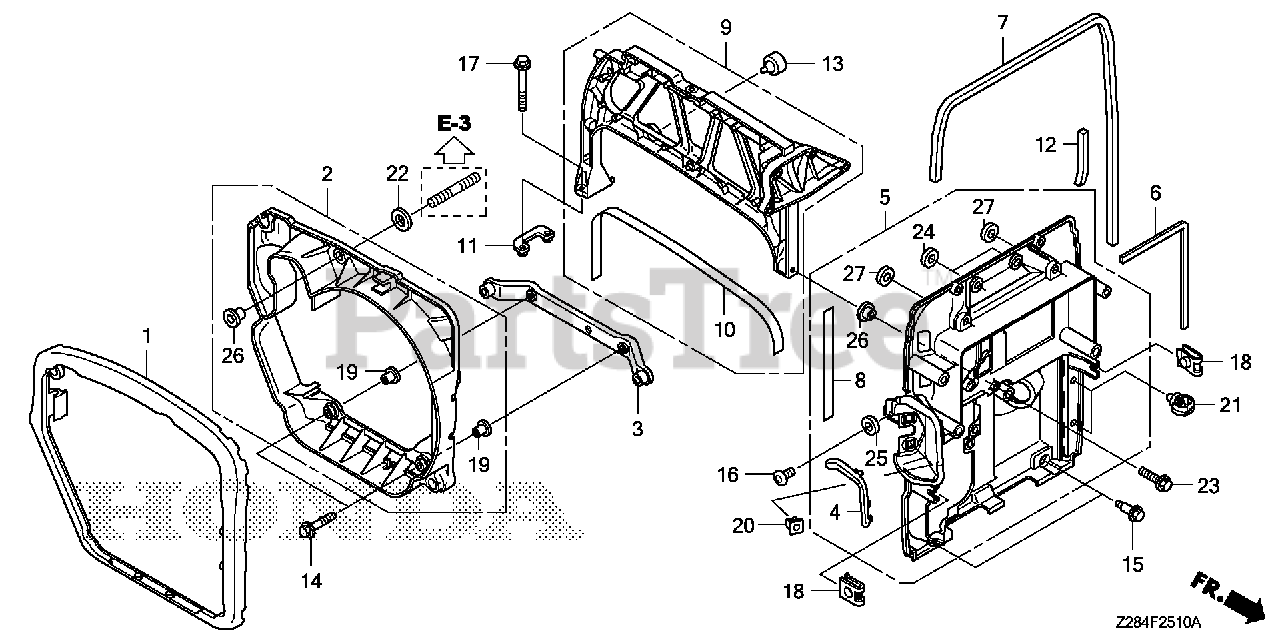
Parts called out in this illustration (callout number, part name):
1	SEAL, FAN COVER
2	GUIDE, FAN COVER
3	BRACKET, FAN COVER
4	PROTECTOR, STARTER ROPE
5	FRAME ASSY., FR.
6	SEAL, FR. FRAME (300MM)
7	SEAL, FR. FRAME (800MM)
8	TAPE, FR. FRAME
9	FRAME ASSY., CENTER
10	TAPE, CENTER FRAME
11	BRACKET, RR. GUARD
12	MAT D, L. RR. COVER (LOWER)
13	RUBBER, STOPPER
14	BOLT, FLANGE (6X30) (CT200)
15	BOLT, SPECIAL (6MM)
16	SCREW, PAN (6X12)
17	BOLT, FLANGE (6X57)
18	NUT, SPRING (6MM)
19	COLLAR, RECOIL STARTER
20	GROMMET, SCREW (6MM)
21	CLIP, WIRE HARNESS (25MM)
22	WASHER, PLAIN (6MM)
23	BOLT, FLANGE (6X20)
24	COLLAR B, FR. FRAME
25	COLLAR, TANK BRACKET
26	COLLAR, RECOIL STARTER
27	COLLAR A, FR. FRAME
